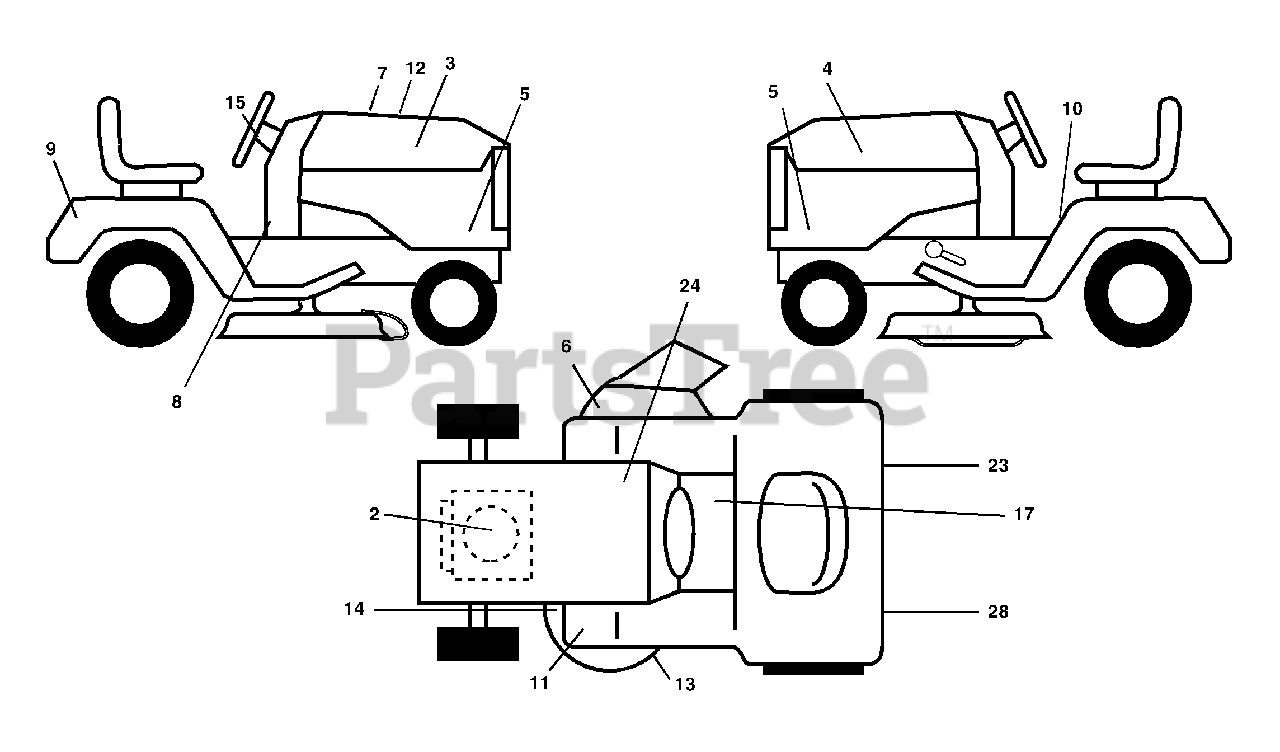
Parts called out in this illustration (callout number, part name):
2	Decal, Engine
3	Decal, Hood, RH
4	Decal, Hood, LH
5	Decal, Side Panel
6	Decal, Warning
7	Decal, Customer Resp.
8	Decal, Dash
9	Decal, Fender
10	Decal, Danger
11	Decal, Foot Rest
12	Decal, Final
13	Decal, V-Belt Sch
14	Decal, Caution
15	Decal, Ins. Strg Whl
17	Decal, Saddle Brake Parking
23	Reflector, Taillight RH
24	Decal, Btry Dngr/Psn
27	Decal, Drawbar
28	Decal, Caution
